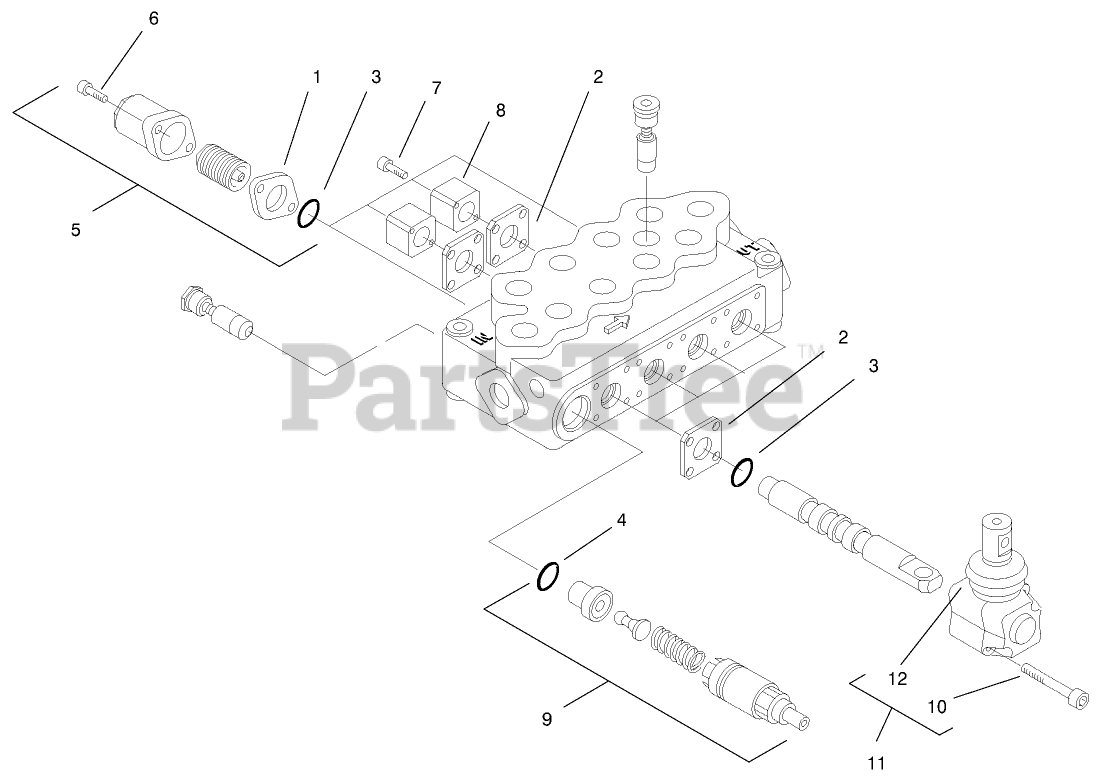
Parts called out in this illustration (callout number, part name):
1	GASKET
2	GASKET
5	STANDARD SPRING KIT
5	HIGH FORCE SPRING KIT
6	SCREW-CAP, END
8	BLOCK-MOUNT, SWITCH
9	VALVE-RELIEF
11	OPERATOR ASM
